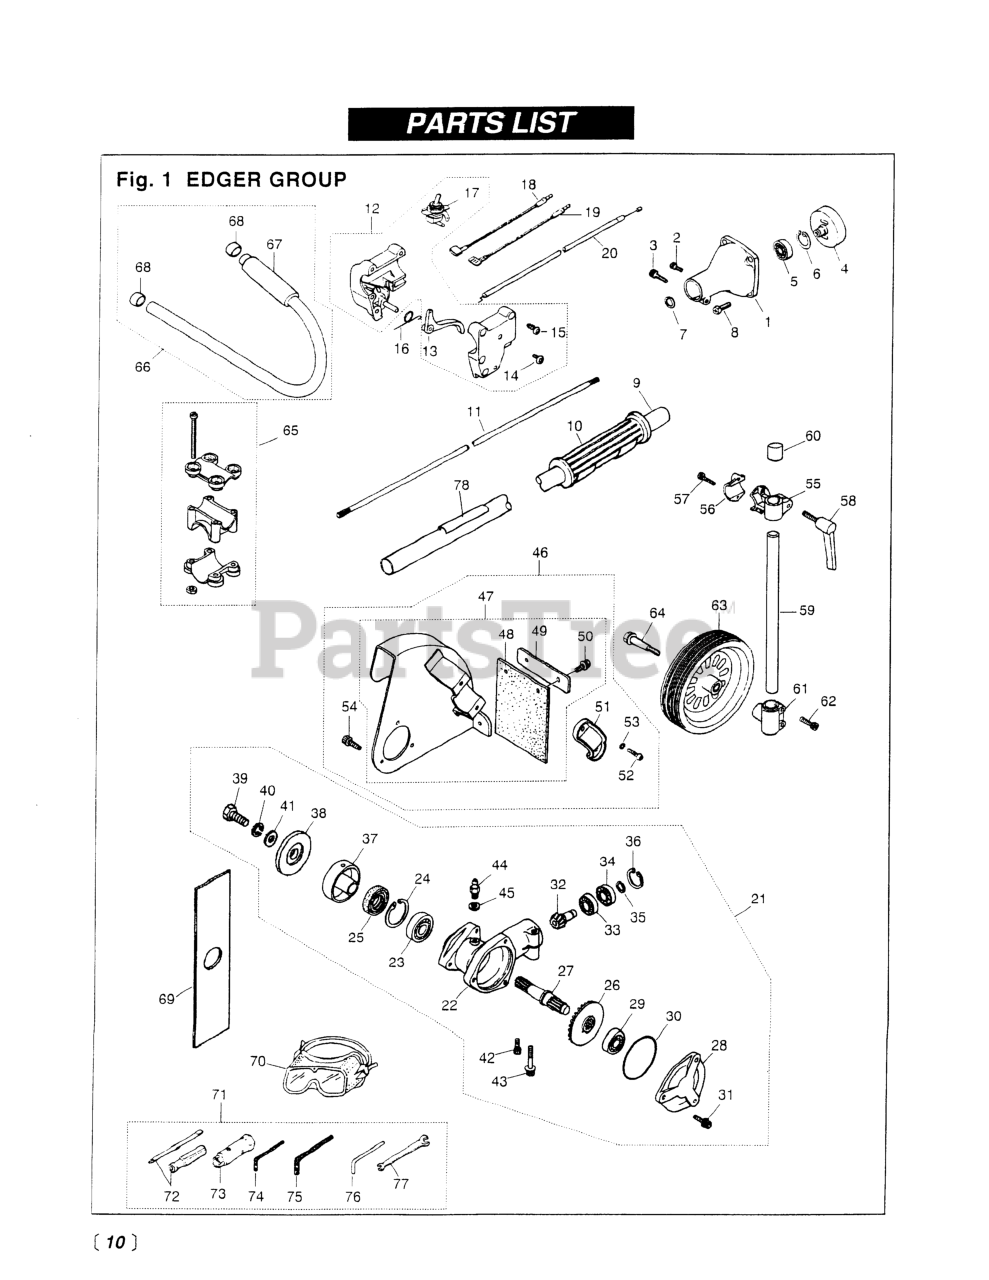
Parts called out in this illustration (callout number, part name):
2	BOLT, M5 X 10
3	BOLT, M5 X 25
5	BEARING
6	RING, SNAP, M28 x 1.2
8	BOLT, M6 x 20
13	LEVER, THROTTLE
14	SET SCREW, ANTI-ROTATION
15	SCREW
16	SPRING, THROTTLE TRIGGER
17	SWITCH, STOP
18	CORD, RED (LEAD WIRE)
19	CORD, BLACK (LEAD WIRE)
20	CABLE COMP (RPLS 6460- )
21	GEARCASE ASSEMBLY
22	GEARCASE
24	RING, SNAP, M32 x 1.2
25	SEAL, OIL
26	GEAR
27	SHAFT, GEAR
28	COVER
29	BEARING (RPLS T3403-13510)
30	O-RING
31	BOLT
32	PINION
33	BEARING (RPLS T3403-13530)
34	BEARING (RPLS T3300-13531)
35	RING, SNAP (RPLS T3300-13330)
36	RING, SNAP, M26 X 1.2
37	HOLDER (A)
38	HOLDER (B)
39	BOLT, LH
40	WASHER (RPLS 3180-13270)
41	WASHER, M8 x 2.3 (RPLS -20823)
42	BOLT, M5 X 10
43	BOLT, M6 x 1.35
44	FITTING, GREASE
45	WASHER, M6 X .8
48	PLATE (RUBBER)
49	PLATE (REPLACES -24130)
50	BOLT, M5 X 12
51	CLAMP
52	BOLT, M6 X 18
53	WASHER, M6 X 15
54	BOLT
55	BRACKET (NLA)
57	BOLT, M5 X 22
58	LEVER
59	TUBE, EDGER
60	CAP
61	BRACKET (NO LONGER AVAILABLE)
62	BOLT, M6 X 25
63	WHEEL, EDGER
64	BOLT
65	HANDLE BRACKET ASSEMBLY
66	J-HANDLE ASSEMBLY
67	GRIP, HANDLE
68	CAP
70	GOGGLE
71	TOOL SET
72	SCREWDRIVER
74	WRENCH (TOOL)
75	WRENCH (TOOL)
76	BAR
77	SPANNER, 8 X 10 (RPLS 2540- )
